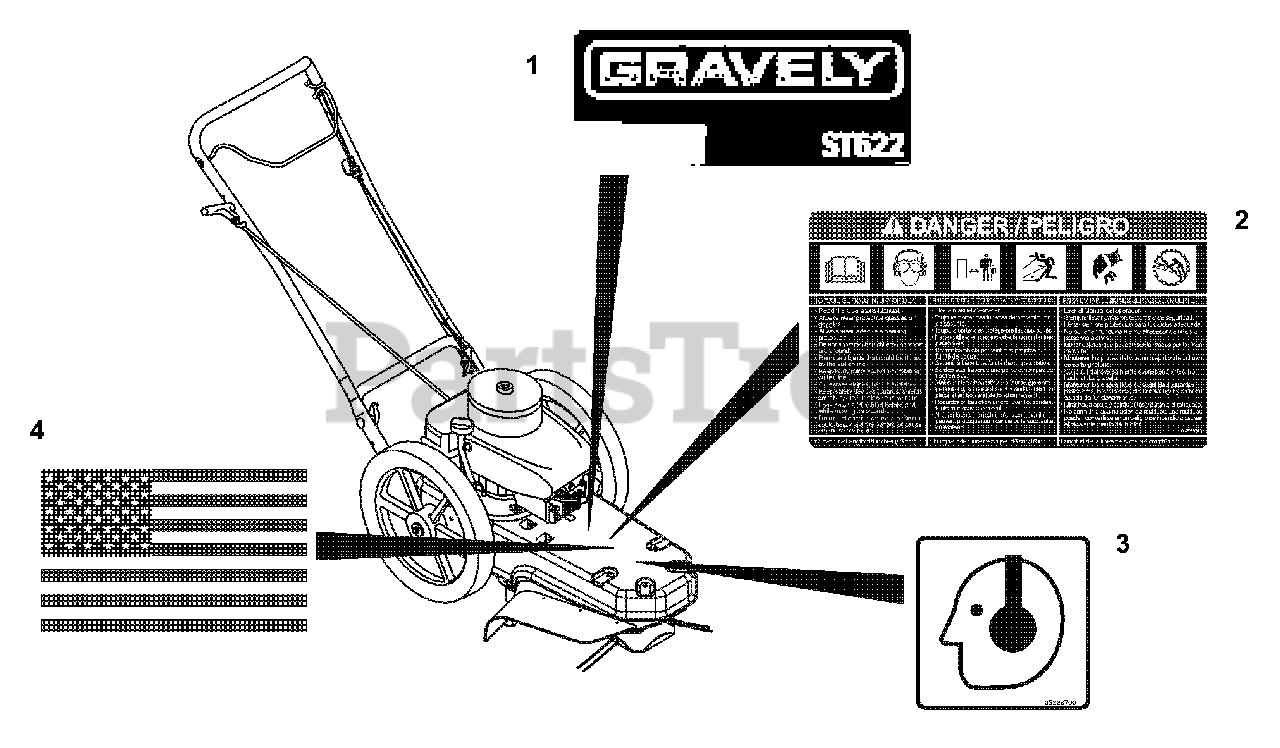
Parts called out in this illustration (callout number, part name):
1	Decal-Gravely ST 622
2	Decal-Danger
3	Decal- Ear Protection (301)
4	Decal - Flag
